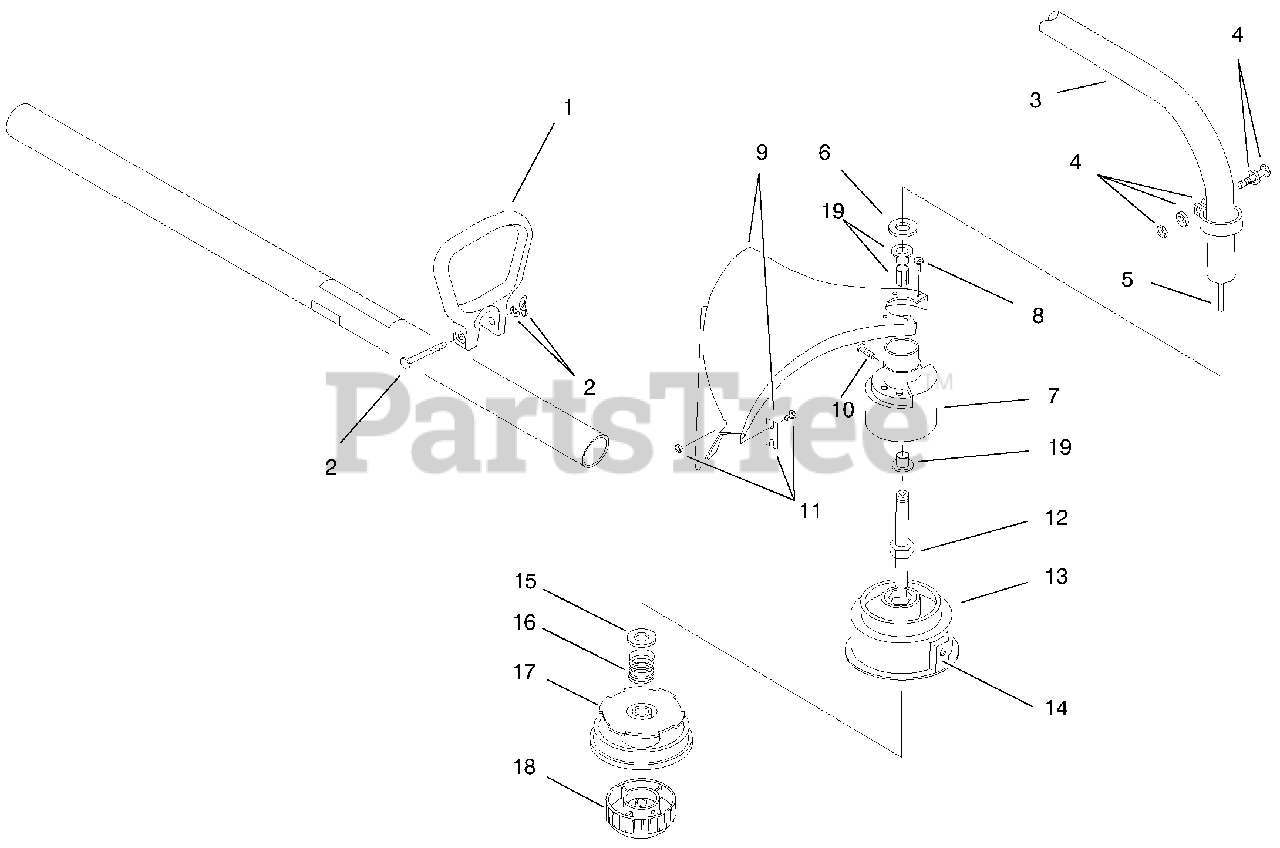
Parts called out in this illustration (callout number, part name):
1	D-Handle
2	D-Handle Hardware Asm.
3	Drive Shaft Housing Asm.
4	Lower Clamp Asm. (Incl. Ref.#10)
5	Flexible Drive Shaft
7	Bushing Housing Asm. (Incl. Ref.# 19)
8	Guard Mounting Screw Asm.
9	Guard & Blade Asm.
10	Anti-Rotation Screw
11	Blade Asm.
12	Spool Shaft
13	Outer Spool & Eyelet Asm.
15	Retainer (10 Pack)
17	Inner Reel
18	Bump Head Knob Asm.
19	Bushing Housing Asm. (Not Serviced Separately)
